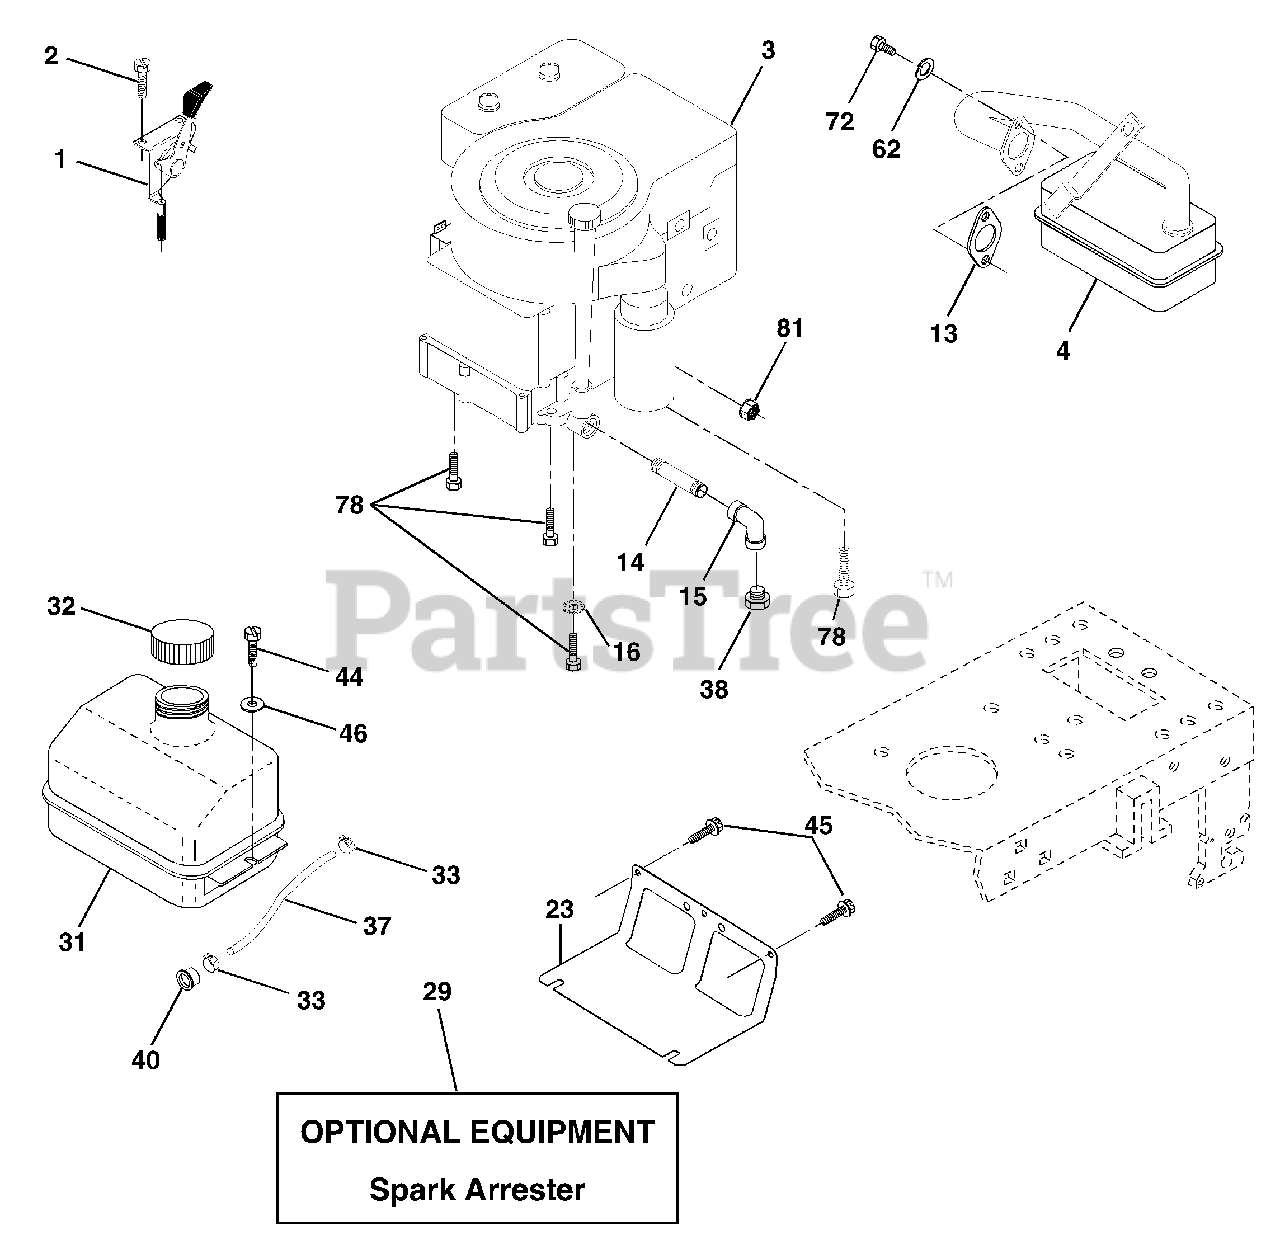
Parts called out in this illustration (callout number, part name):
1	Control Th/ch Flag
2	Screw Hex Thd Cut 1/4-20 x 1/2
4	Muffler Exhaust B&S
13	Gasket Eng 1 313 Id Tin Plated
14	Nipple Pipe 3/8 NPT x 3
15	Elbow Std 90 Degree 3/8-18 NPT
16	Washer Lock Ext Tooth 3/8
23	Shield BRN/DBR Guard
29	Kit Spark Arrestor (Flat Scrn)
31	Tank Fuel Front
32	Cap Asm Fuel
33	Clamp Hose
37	Line Fuel 20"
38	Plug Drain Oil
40	Bushing Snap Nyl Blk Fuel Line
44	Screw Thdrol 1/4-20 x 3/4
45	Screw Hex Wsh Thdrol 3/8-16
46	Washer 9/32 X 7/8 X 16 Ga
62	Washer Lock Hvy Hlcl Spr
72	Screw Hexcap 5/16-18 x 3/4
78	Screw 3/8-16 x 1-1/4
81	Nut Keps Hex 1/4-20 Unc
